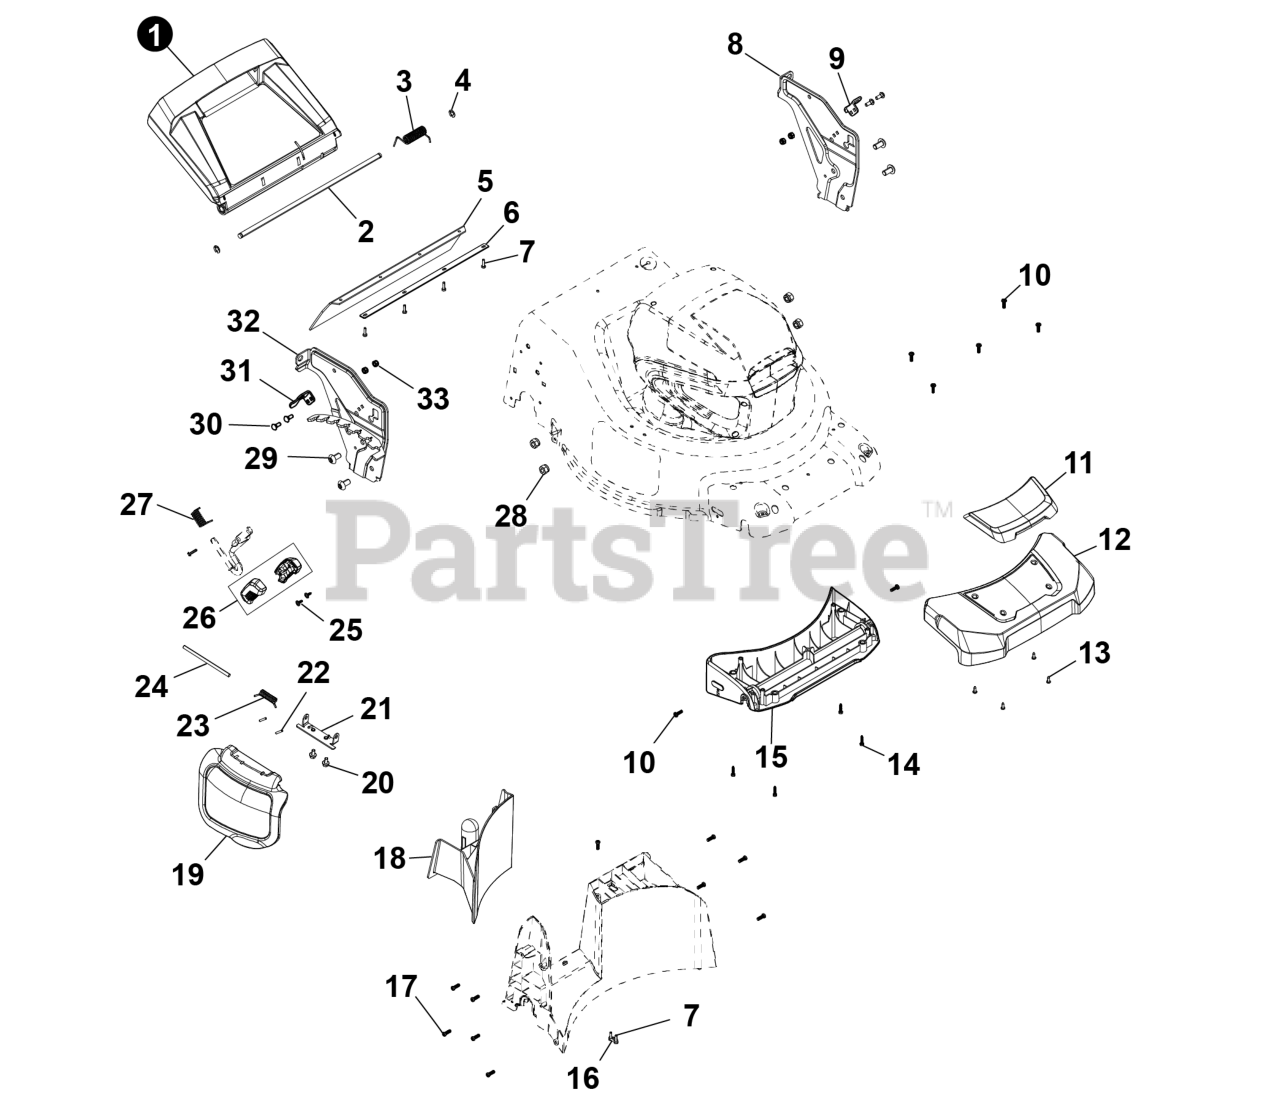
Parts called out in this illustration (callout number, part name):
1	DOOR, REAR
2	ROD,REAR DOOR
3	SPRING, TORSION
5	SHIELD, DEBRIS
6	PLATE, RETAINER
8	PLATE,LEFT HEIGHT ADJ.
9	PLATE,LEFT LATCH
11	COVER, DECORATIVE
12	COVER, FRONT
15	COVER,LOWER BUMPER
16	RETAINER
18	PLUG, MULCH
19	COVER, SIDE DISCHARGE
20	BOLT, FLANGE
21	BRACKET, SIDE DISCHARGE
22	SLEEVE, RUBBER
23	SPRING, TORSION
24	SHAFT, SIDE DISCHARGE
25	SCREW, PAN HEAD SELF TAP
26	HANDLE, HEIGHT ADJUSTMENT
27	SPRING, TORSION
28	NUT, NYLOC
31	PLATE,RIGHT LATCH
32	PLATE,RIGHT HEIGHT ADJ.
